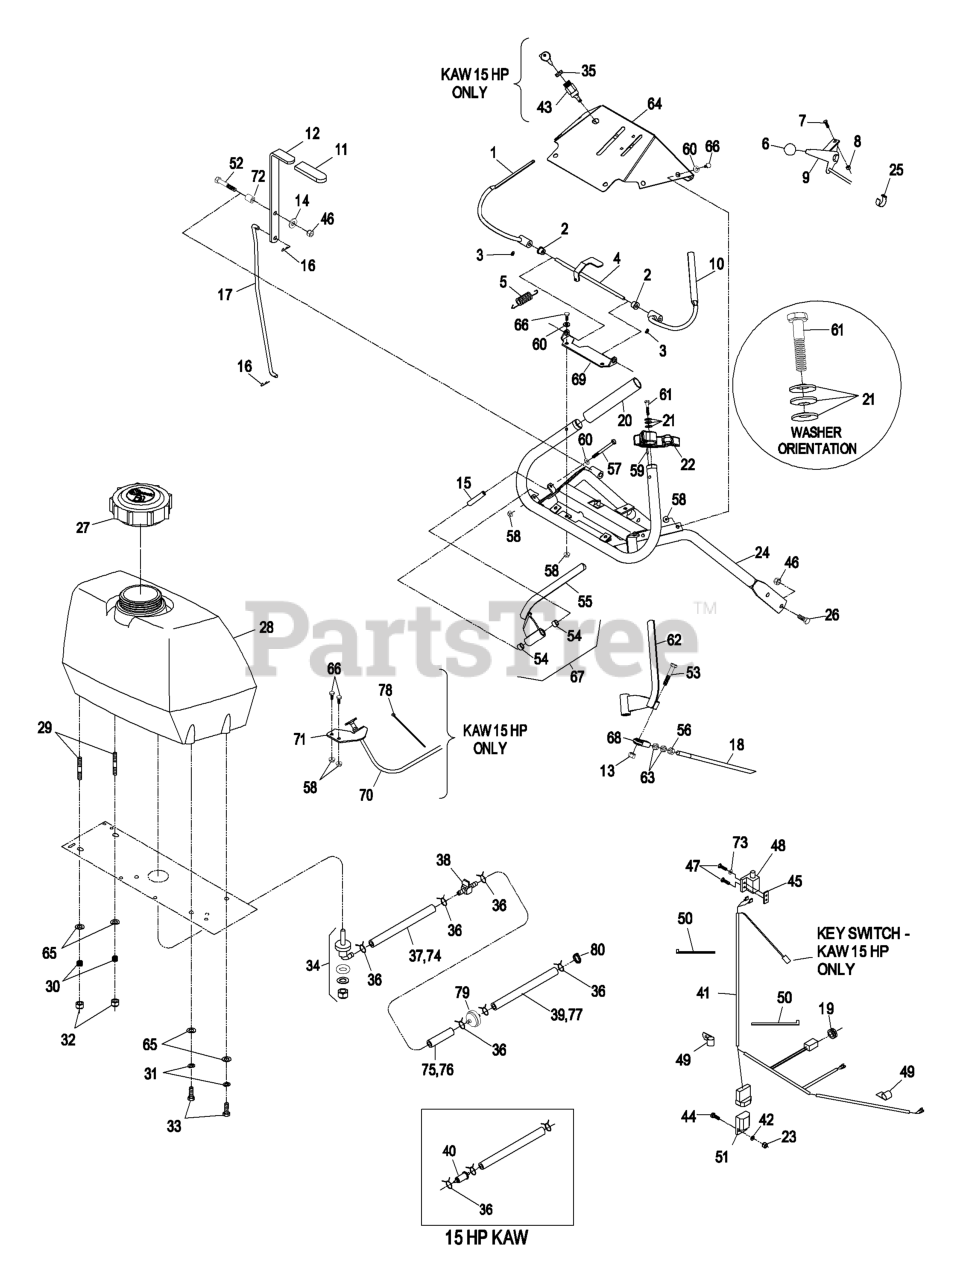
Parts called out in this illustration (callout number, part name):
2	BUSHING-NYLON
3	SCREW-SET
4	WLD,OPC LEVER AXLE
5	SPRING-EXTENSION
6	KNOB-BALL
7	BOLT-CARR
8	NUT-LOCK, NI
9	THROTTLE CABLE ASM
11	GRIP-LEVER
12	CLUTCH LEVER-W/GRIP
13	NUT-LOCK, NI
14	WASHER-FLAT
15	BUSHING-LEVER, DRIVE
16	PIN-COTTER
17	LINKAGE,UPPER BLADE (PLT)
18	LINKAGE,DRIVE (PLT)
19	GROMMET
20	GRIP-BAR, HANDLE
21	WASHER-SPRING
22	ASM,LH THUMB LATCH
23	NUT-LOCK, NI
24	WLD,UPPER ECS HANDLE
25	CLIP-CABLE
26	SCREW-HH
29	STUD
30	SPRING-TANK, FUEL
31	WASHER-LOCK
32	NUT-LOCK, NI
33	SCREW-HH
34	FITTING-FUEL, BULKHEAD
35	NUT-SWITCH, IGNITION
37	HOSE-FUEL
38	VALVE-FUEL
39	HOSE-FUEL
40	Kawasaki Pn 41019-1055 W/6" Fuel Line
41	HARNESS-WIRING
42	WASHER-FLAT
43	SWITCH & KEY (INCLUDES NU
44	SCREW-HH
45	PLATE-TAPPED
46	NUT-LOCK, NI
47	SCREW-PPH
48	SWITCH-OPEN, NORMALLY
49	CLIP-LOOM
50	TIE-CABLE
51	MODULE-INTERLOCK
52	SCREW-CARR
53	SCREW-HH
54	BUSHING-SLEEVE
56	NUT-HEX
57	SCREW-HH
60	WASHER-FLAT
61	SCREW-HH
63	NUT-HJ
65	WASHER-PLAIN
66	SCREW-HH
67	DRIVE LEVER-ASM, RH
68	JOINT-BALL, END
69	BRACKET,OPC AXLE
70	CABLE-CHOKE
71	BRACKET-CABLE, CHOKE
72	BUSHING-LEVER, LIFT
73	WASHER-FLAT
74	HOSE-FUEL
75	HOSE-LINE, FUEL
76	HOSE-FUEL
77	HOSE-LINE, FUEL
78	TIE-PLASTIC
80	CLAMP-HOSE
